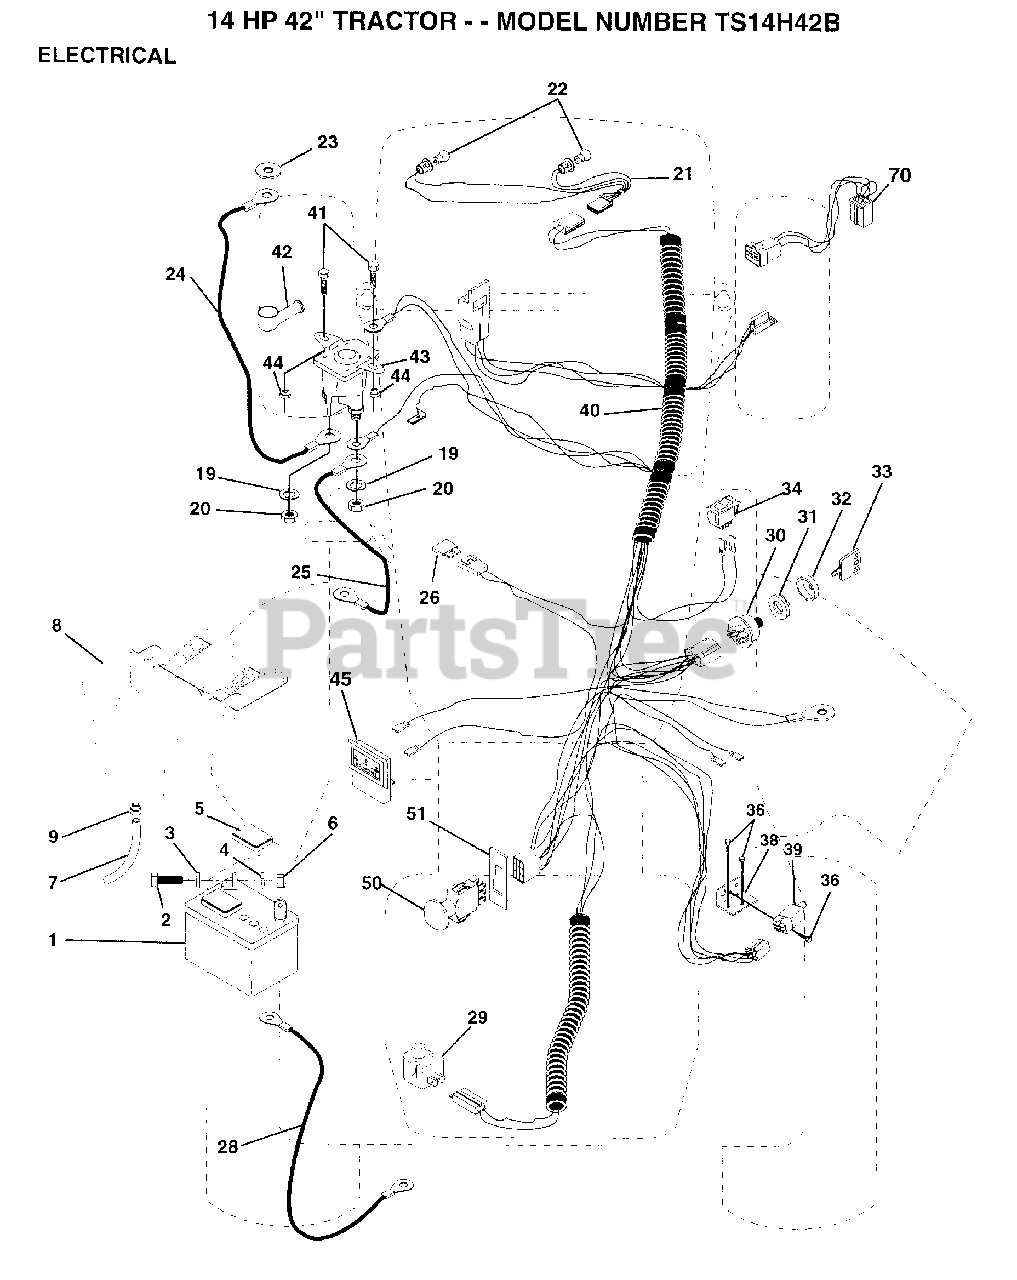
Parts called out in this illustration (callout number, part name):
2	BOLT LT
3	WASHER
4	LOCKWASHER
5	"CAP,BATTERY "
7	TUBE T
9	PLATE T
20	NUT
21	"HARNESS,LIGHT SOC"
22	HEADLAMP BULB
23	LOCKWASHER
24	CABLE-BATTERY T
26	FUSE HYT
28	CABLE T
29	SWITCH SEAT
32	COVER KEY SWITCH
33	KEY MLD GEN DELTA
34	SWITCH LT
36	SCREW
38	BRACKET SWITCH IN
39	SWITCH INTERLOCKT
40	HARNESS.IGN.PTO
41	BOLT HXHD FIN
44	NUT HXKEP 1/4X20
45	AMMETER
51	RING RETAIN PTO
70	HARNESS ENG 11GA
